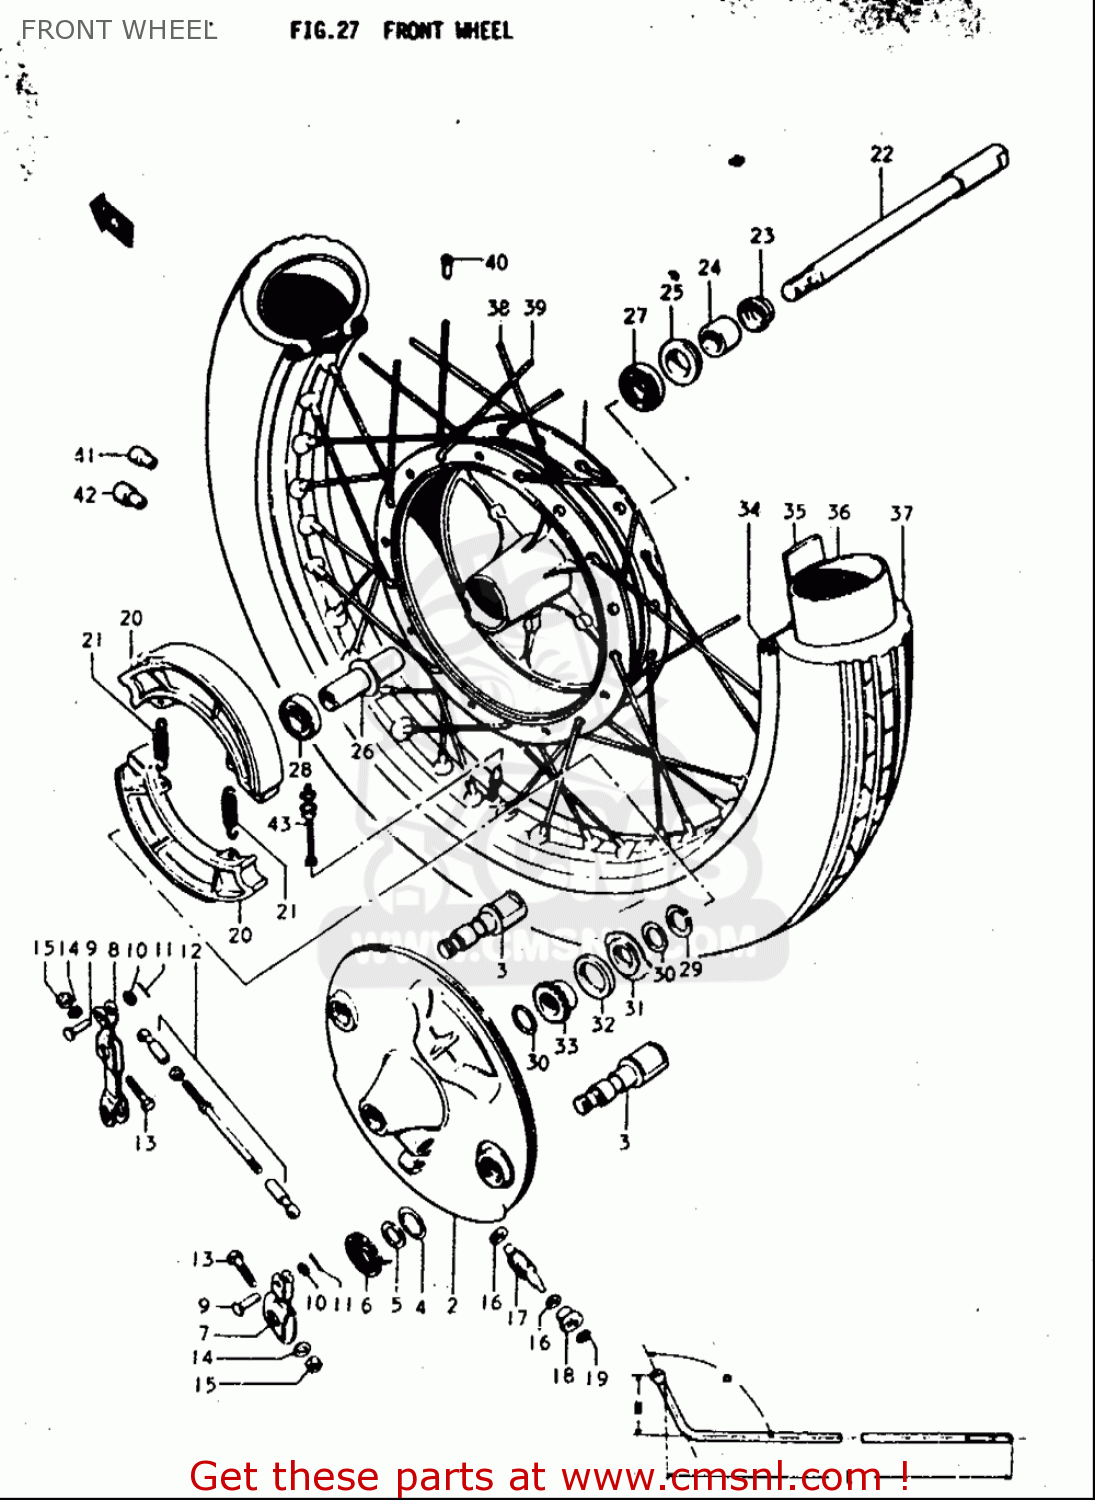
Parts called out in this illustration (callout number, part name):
3	CAM,RR BRAKE
4	O RING(D:2.4,ID:14.8)
5	WASHER(15.5X24X1.6)
6	SPRING
10	WASHER
11	PIN 12X10
13	BOLT(6X31)
14	WASHER
15	NUT
16	WASHER(5.1X9X0.4)
17	PINION,SPEEDOMETER
18	BUSHING,SPEEDOMETER PINION
19	SEAL,OIL(6X10X3)
21	SPRING,BRAKE SHOE
22	AXLE,FRONT
24	SPACER
26	SPACER,FRONT HUB BEARING
27	BEARING
28	BEARING
29	CIRCLIP
30	WASHER(22.5X27X1)
31	DRIVER,SPEEDOMETER GEAR
32	SEAL,OIL(26X38X4)
35	PROTECTOR,INNER TUBE
36	TUBE ASSY,INNER
37	SPOKE SET,RR WHEEL
41	BALANCER,WHEEL (B)
42	BALANCER,WHEEL (30G)
